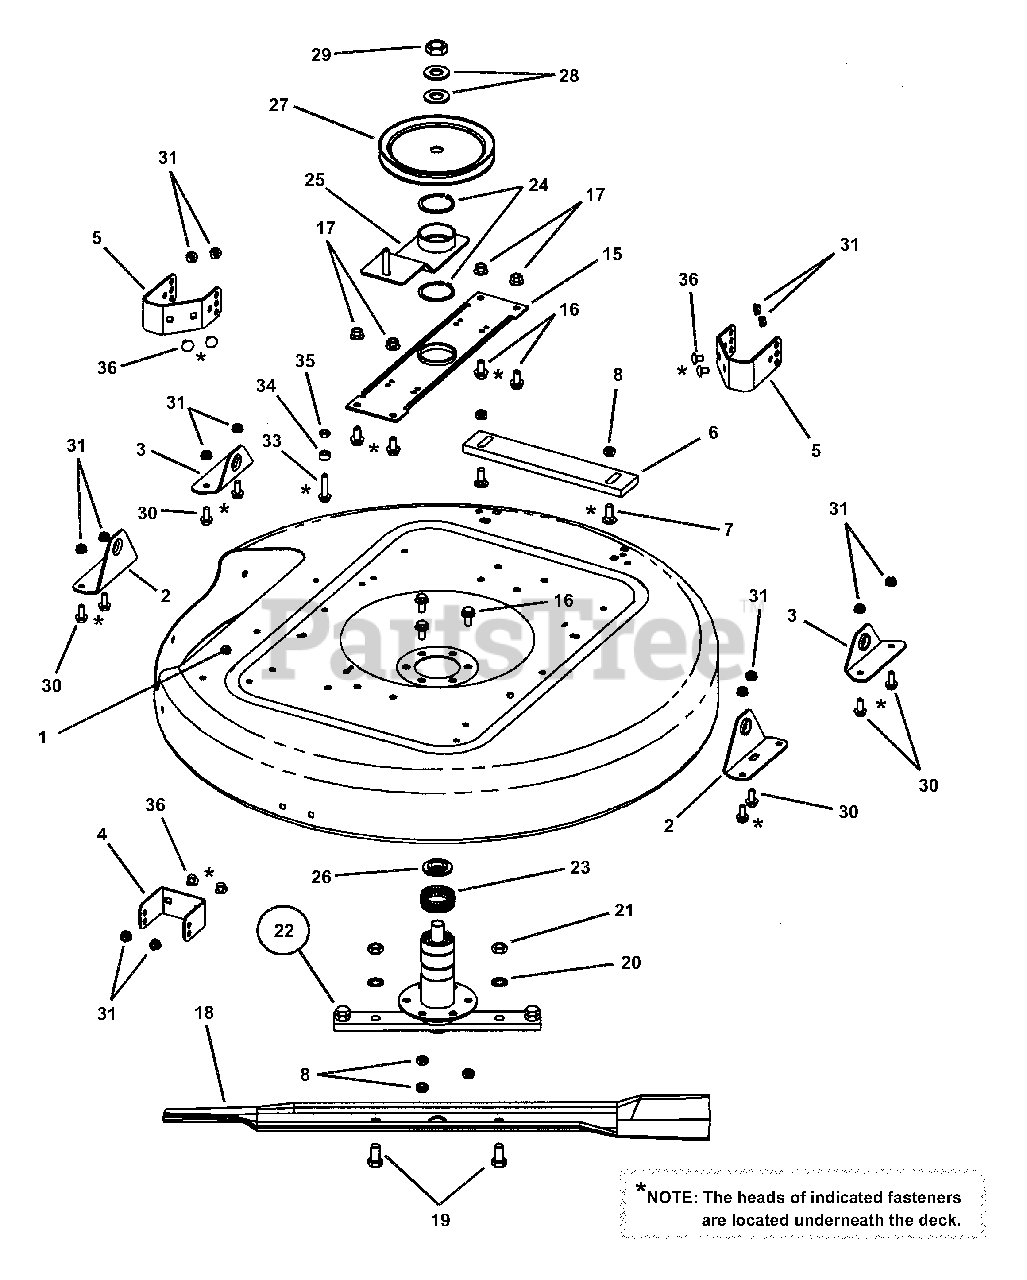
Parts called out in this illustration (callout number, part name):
1	DECK, 33" Replacement
2	BRACKET, Deck Lift Slotted
3	BRACKET, Deck Lift
4	BRACKET, Anti-Scalp Adj. Front
5	BRKT., Anti-Scalp Adj. Side
6	BAR, Weight Rear
7	BOLT, 3/8-16 x 1" Carriage
8	NUT, 3/8-16 Hex Center Lock
15	BRACE, Spindle
16	BOLT, 3/8-16 x 3/4" Hex Flange Lock, Grade 5
17	NUT, 3/8-16 Hex Flange Lock
18	BLADE, 33" High Lift
19	SCREW, 1/2-20 x 1" Hex Head Cap, Grade 5
20	WASHER, 1/2" Internal Tooth Lock
21	NUT, 1/2-20 Hex Jam
22	ASSEMBLY, Spindle
23	RING, 2" Tolerance
24	RING, 2" External Retaining
25	ARM, Idler (weldment)
26	WASHER, Spindle
27	PULLEY, Spindle
28	WASHER, 25/32" Flat
29	NUT, 3/4-16 Hex Jam, Grade 8
30	BOLT, 5/16-18 x 3/4" Hex Flange Lock
31	NUT, 5/16-18 Hex Fl. Lock
33	BOLT, 5/16-18 x 1-1/2" Hex Flange Lock, Grade 5
34	SPACER, 11/32"
35	NUT, 5/16-18 Hex Lock
36	BOLT, 5/16-18 x 1/2" Short Neck Carriage
